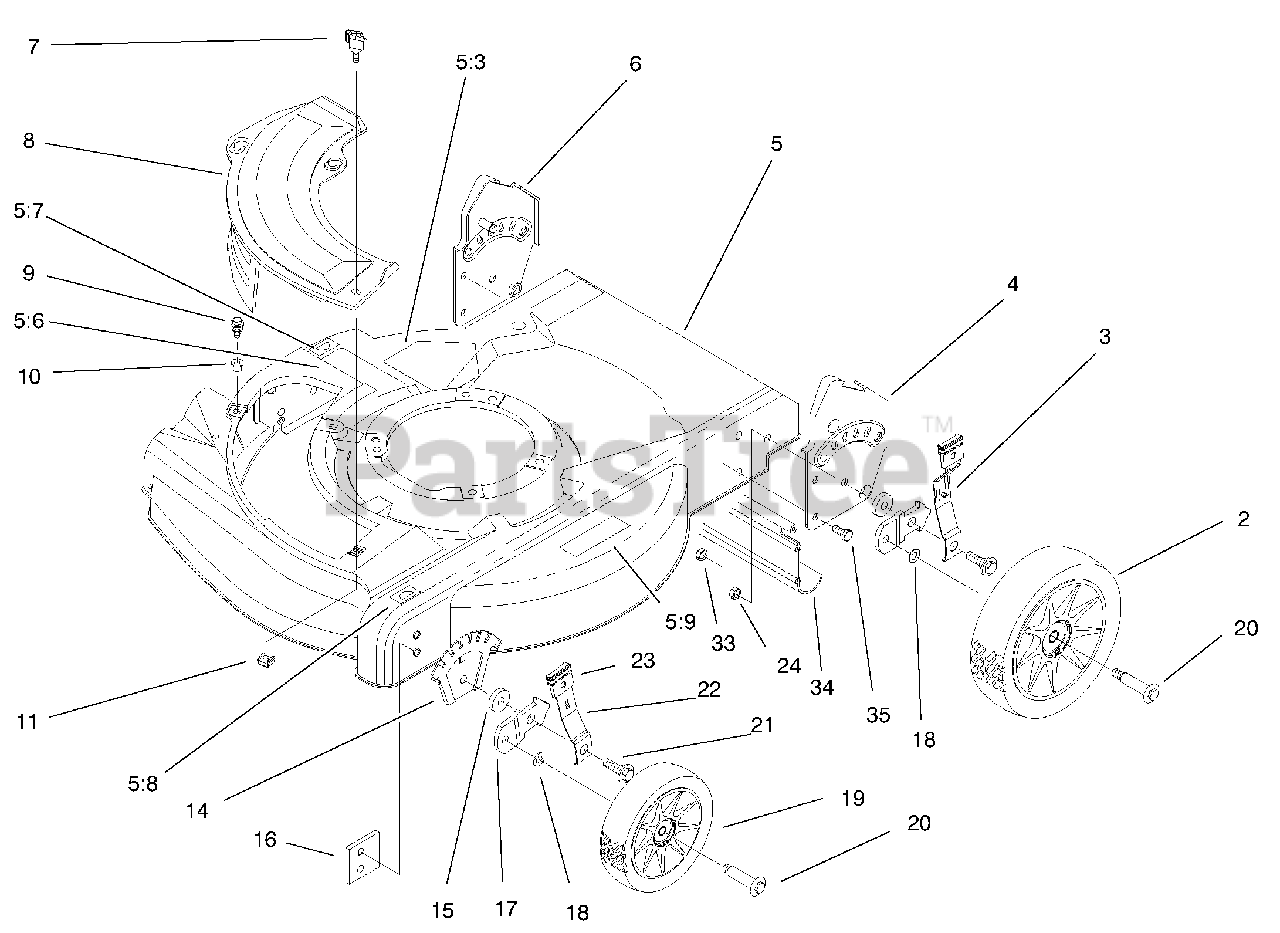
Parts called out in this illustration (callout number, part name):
3	Spring Arm ASM-Rear
4	LH Handle Brkt ASM
5	ASM-Hsg/Baffle w/Decals
5:3	Decal-Danger
5:6	Decal-Warning
5:7	Decal-HOC R
5:8	Decal-HOC L
5:9	Decal-Safety Instruct
6	RH Handle Brkt ASM
8	Plate-Mulch
9	Screw-Sems
10	Grommet-Plastic
11	Nut-Cage
14	Plate-Hght Adj
15	Washer-Wheel
16	Plate-Baffle
17	Bracket-Wheel Ht Adj
18	Washer-Wheel Bolt
20	Bolt-Shoulder 6" Wheel
21	Bolt-Shoulder
22	Arm-Front Spring
23	Knob-Height Adj Lever
24	Nut-Lock NI
26	Strap-Tie Sm
33	Nut-Lock NI
34	Shield-Trailing
35	Screw-HH
36	Plate-Chute Opening
